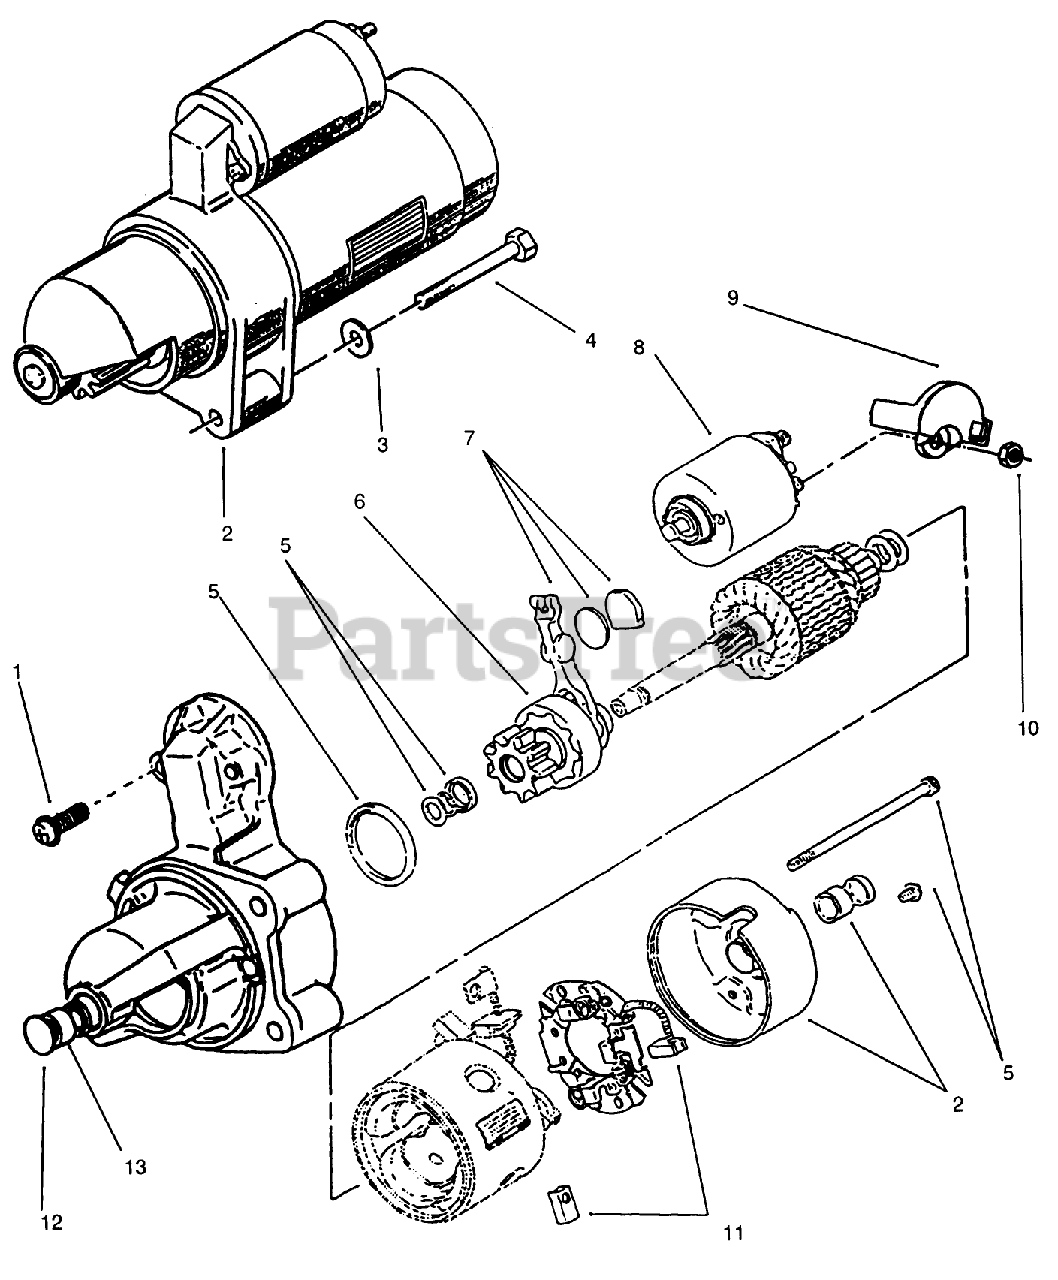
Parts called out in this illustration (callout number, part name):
3	WASHER
12	BUSHING
13	KIT-MTG BRKT
